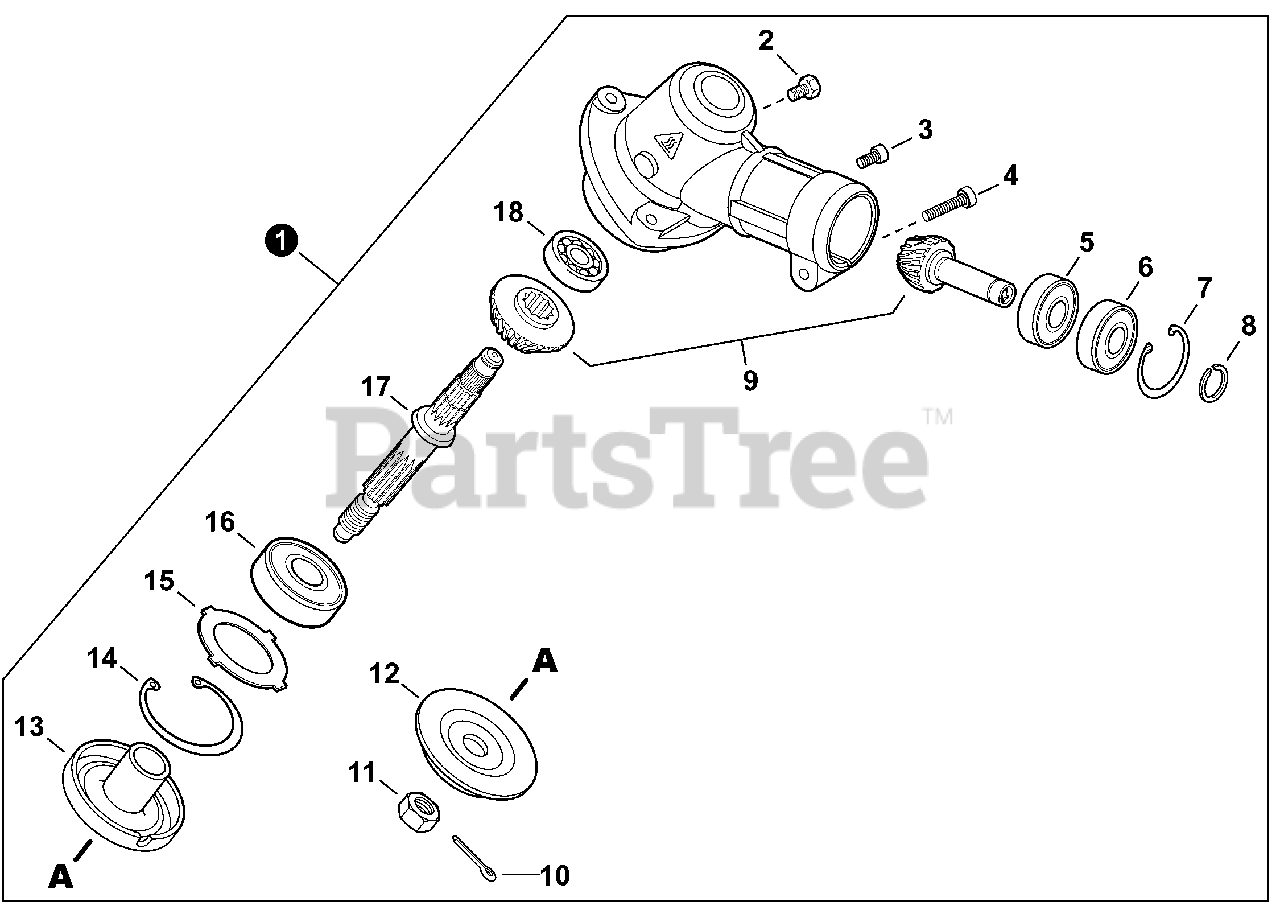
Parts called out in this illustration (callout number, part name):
1	GEAR CASE ASSY
2	BOLT M8×8
3	BOLT, TORX 5×10
4	BOLT, TORX 5×25
5	BEARING, BALL 609
6	BEARING, BALL 609
7	RING, SNAP Ø25
8	RING, SNAP Ø9
9	GEAR SET
10	PIN, COTTER 2×22
12	PLATE, ADAPTOR - LOWER
13	PLATE, ADAPTOR - UPPER
14	RING, SNAP Ø32
16	BEARING, BALL 6201
17	SHAFT, GEAR
18	BEARING, BALL 629
